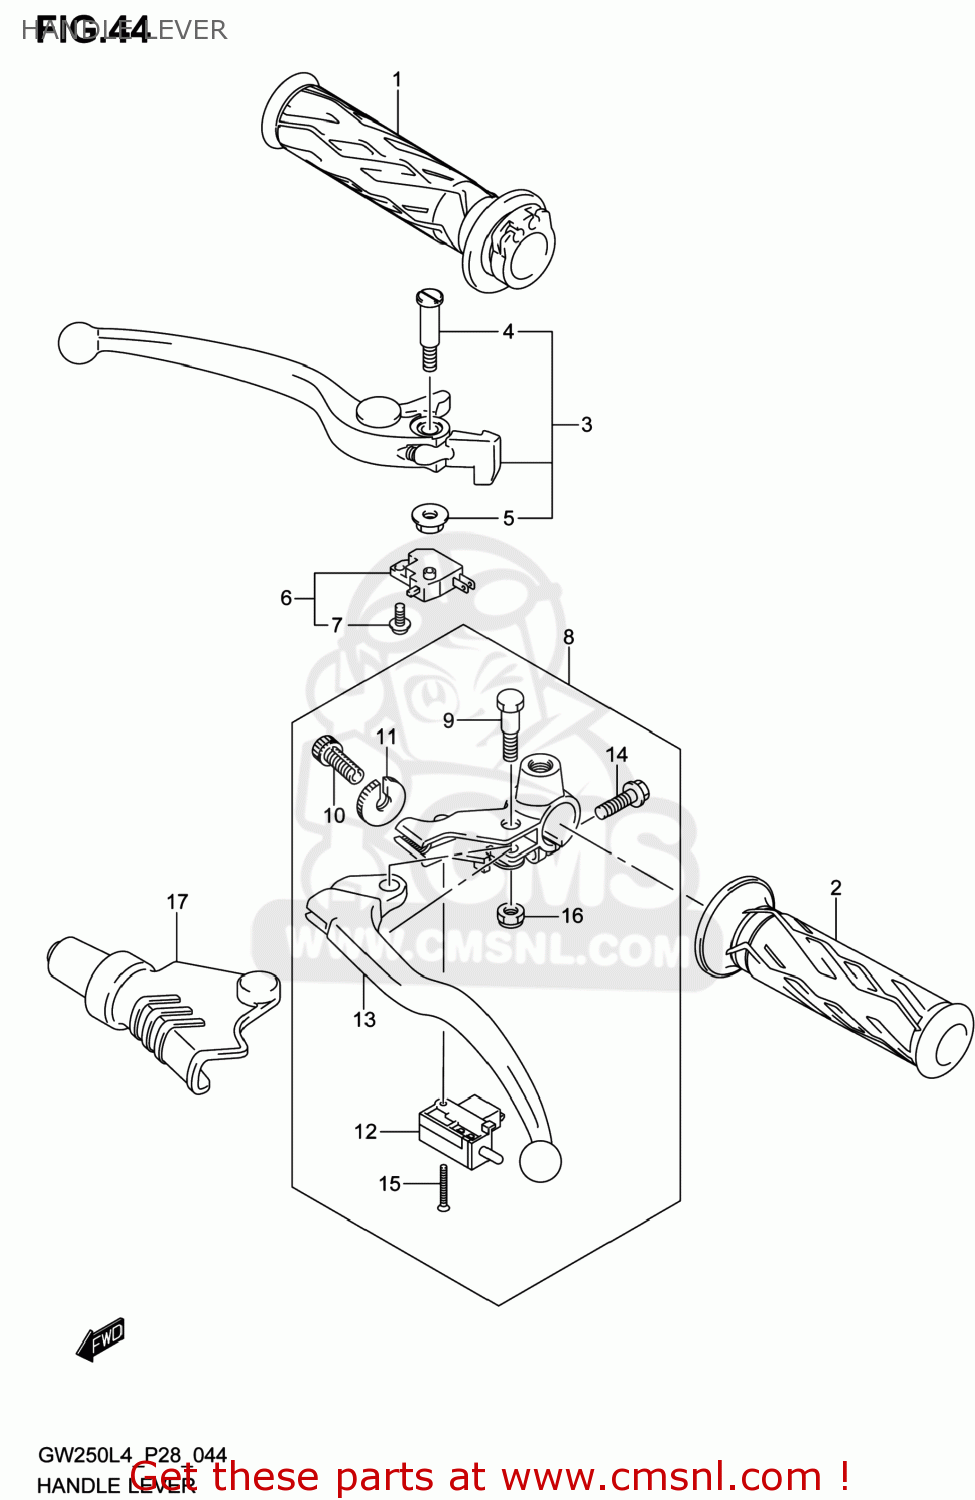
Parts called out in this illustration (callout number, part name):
1	GRIP,THROTTLE
2	GRIP,L
3	LEVER ASSY,BRAKE
4	BOLT,LEVER PIVOT
5	NUT
6	SWITCH ASSY,FR BRAKE
7	SCREW
8	LEVER ASSY,CLUTCH
9	BOLT,LEVER PIVOT
10	ADJUSTER,WIRE
11	NUT,LOCK
12	SWITCH ASSSY,CLUTCH
13	LEVER,CLUTCH
14	BOLT
15	SCREW
16	NUT
17	COVER,CLUTCH LEVER
